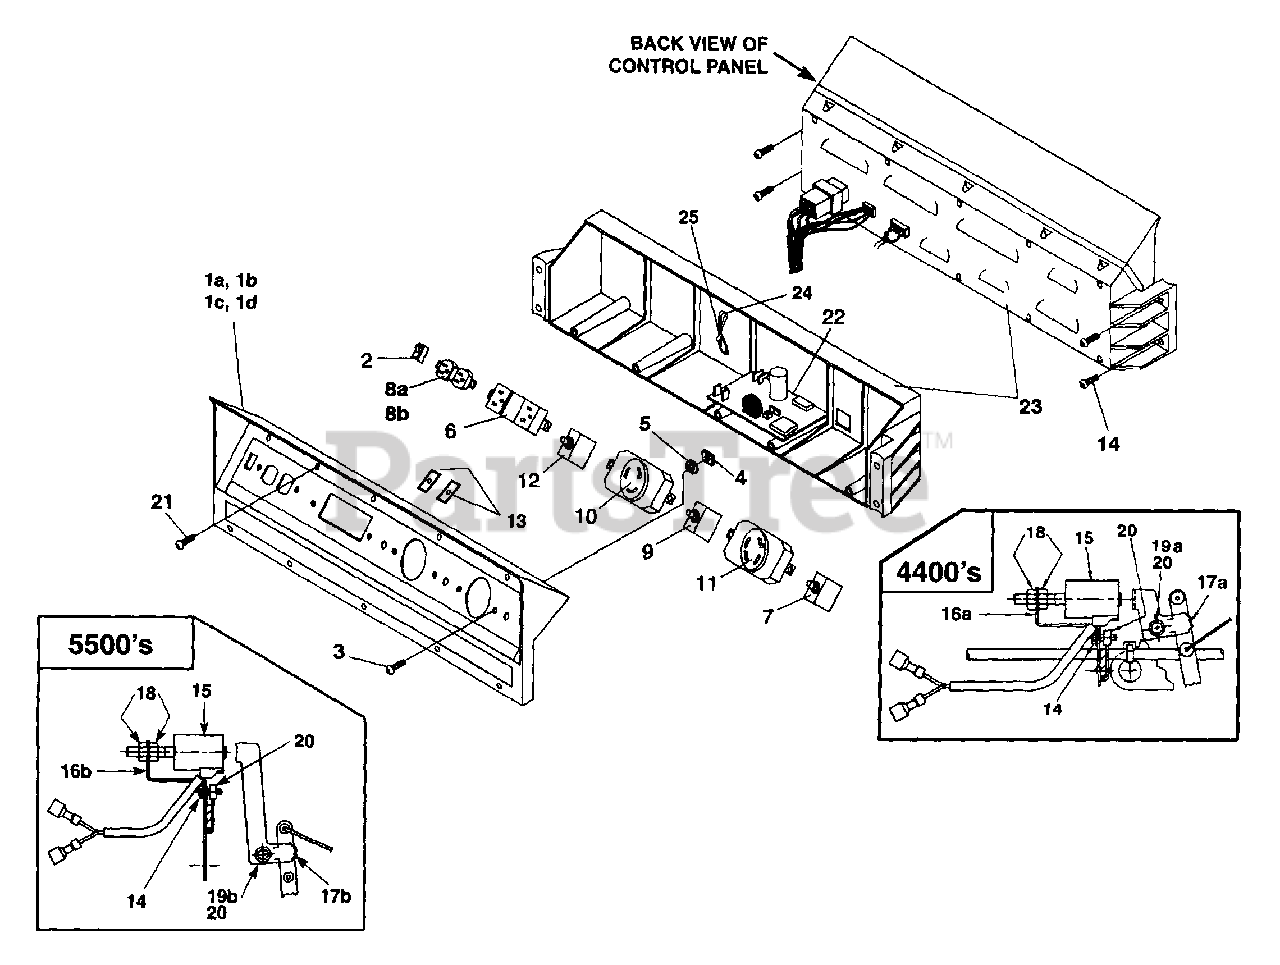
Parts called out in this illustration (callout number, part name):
1A	CONTROL PANEL (LRI4400, LRIE4400)
1B	CONTROL PANEL (LRI5500, LRIE5500)
1C	CONTROL PANEL (LRI4400/CSA, LRIE4400/CSA)
1D	CONTROL PANEL (LRI5500/CSA, LRIE5500/CSA)
2	SWITCH
3	SCREW-Pan Hd. (8-32 X 7/8")
4	NUT-Hex
5	WASHER-Lock
6	RECEPTACLE (GFCI)
7	CIRCUIT BREAKER (20 amp)
8A	RECEPTACLE-Duplex (LRI4400, LRIE4400, LRI5500, LRIE5500)
8B	RECEPTACLE-Duplex (120 V) (LRI4400/CSA)
9	CIRCUIT BREAKER (30 amp)
10	RECEPTACLE-Locking (120V)
11	RECEPTACLE-Locking (240V)
12	CIRCUIT BREAKER (15 amp)
13	RUBBER BUMPER
14	SCREW-Torx Hd. (10-24 X 1/2)
15	ELECTROMAGNET
16A	BRACKET (8HP) (4400's)
16B	BRACKET (11HP) (5500's)
17A	PADDLE (8HP) (4400's)
17B	PADDLE (11HP) (5500's)
18	NUT-Hex (1/4-28) (4400 & 5500)
19A	SCREW-Hex Hd. (1/4-20 X 5/8") (4400 & 5500)
19B	SCREW-Hex Hd. (1/4-20 X 5/8") (4400 & 5500)
20	SPEED Nut (8-32) (4400 & 5500)
21	SCREW-Plastite (8-16 X 3/4")
22	CONTROL BOARD
23	CONTROL PANEL-Back
24	TIE, Cable
25	Clip, Tie
